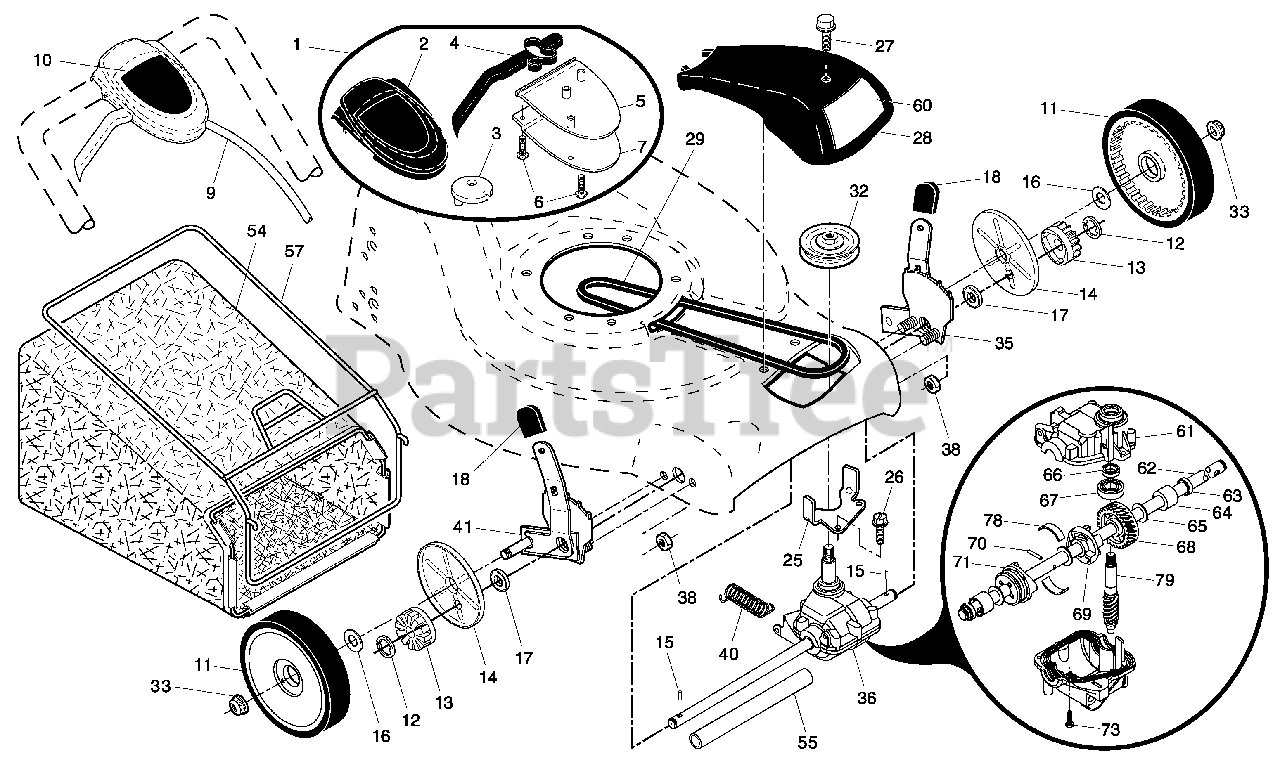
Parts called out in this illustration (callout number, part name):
1	Drive Control Assembly
2	Cover, Drive Control, Upper
3	Pulley
4	Lever, Drive Control
5	Cover, Drive Control, Lower
7	Bracket, Drive
9	Cable Assembly, Drive
10	Decal, Drive
11	Wheel & Tire Assembly
14	Dust Cover
15	Pawl, Drive
16	Washer 1/2 x 1-1/2 x .134
17	Bearing, Wheel Adjuster
18	Selector Knob
25	Belt Keeper
26	Screw, Hi-Lo Thread
27	Pan Head Tapping Screw #10-24 x 2-3/4
28	Drive Cover
32	Drive Pulley
33	Locknut, Hex
35	Kit, Wheel Adjuster, LH
36	Gearcase Assembly, Complete
38	Locknut, Hex 1/4-20
41	Kit, Wheel Adjuster, RH
54	Grassbag Assembly
55	Driveshaft Cover
57	Frame, Grassbag
60	Decal, Drive Cover
61	Case, Upper
62	Shaft, Output
63	Seal, Output Shaft
66	Seal, Worm Shaft
67	Bearing, Ball
68	Gear, 28 Teeth
69	Fixed Dog Clutch
70	Pin
71	Movable Dog Clutch
73	Screw, Case
74	Case, Lower
78	Spring, Leaf
79	Shaft, Worm
